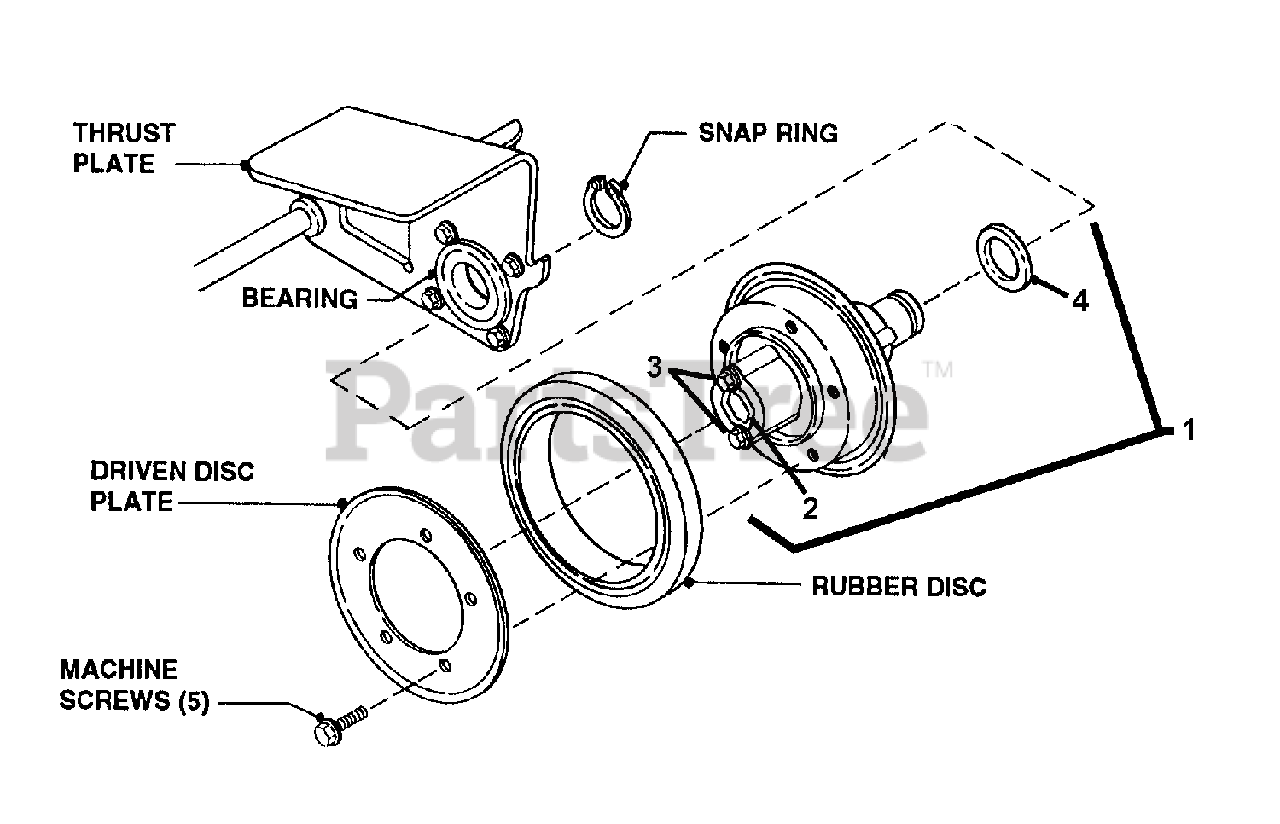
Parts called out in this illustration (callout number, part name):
1	KIT, Driven Disc Hub Replacement
2	DRIVE BUSHING-HEX
3	HWST, 10C-1/2 TORX
4	WASHER, SHIM .75X1.0X.021
